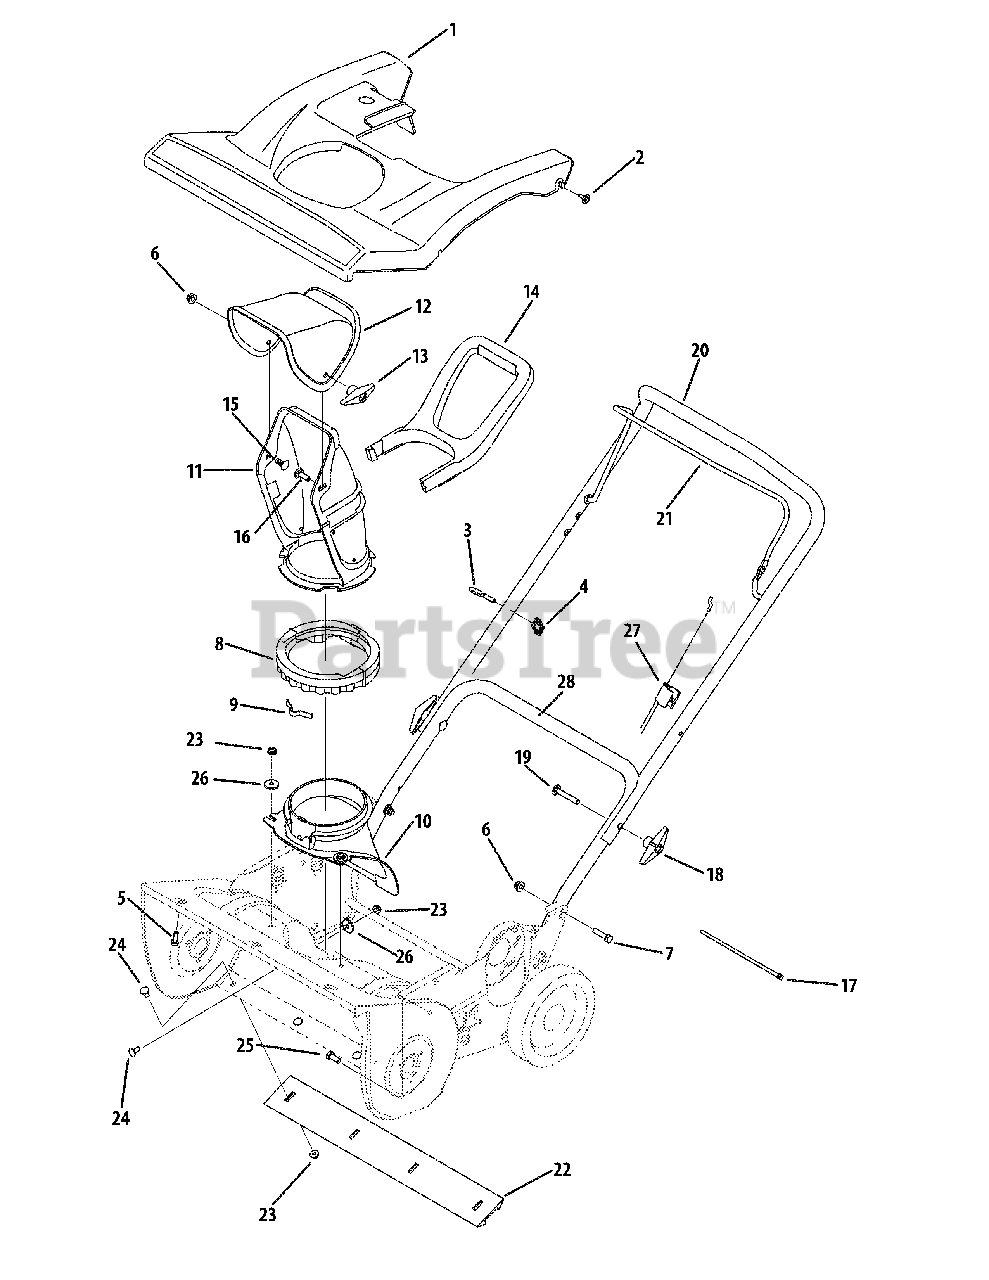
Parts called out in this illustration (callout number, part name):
2	Hex Washer Screw, 10-16 x .625
3	Eye Bolt, 1/4-20
4	Knob Handle
5	Hex Washer Screw, 1/4-15 x .750
6	Flange Lock Nut, 5/16-18
7	Hex Screw, 5/16-18 x 1.25
8	Lower Chute Ring
9	Chute Adjustment Spring
10	Chute Adapter
11	Lower Chute, 5" Diameter
12	Upper Chute
13	Wing Knob
14	Chute Handle
15	Carriage Bolt, 5/16-18 x .750
16	Carriage Bolt, 5/16-18 x 1.00
17	Cable Tie, 3/16 x .05 x 7.4
19	Carriage Screw, 5/16-18 x 2.00
22	Shave Plate, 21"
23	Flange Lock Nut, 1/4-20
24	Carriage Screw, 1/4-20 x .62
25	Hex Screw, 5/16-18 x .75
26	Flat Washer, .265 x .938 x .120
27	Clutch Cable
